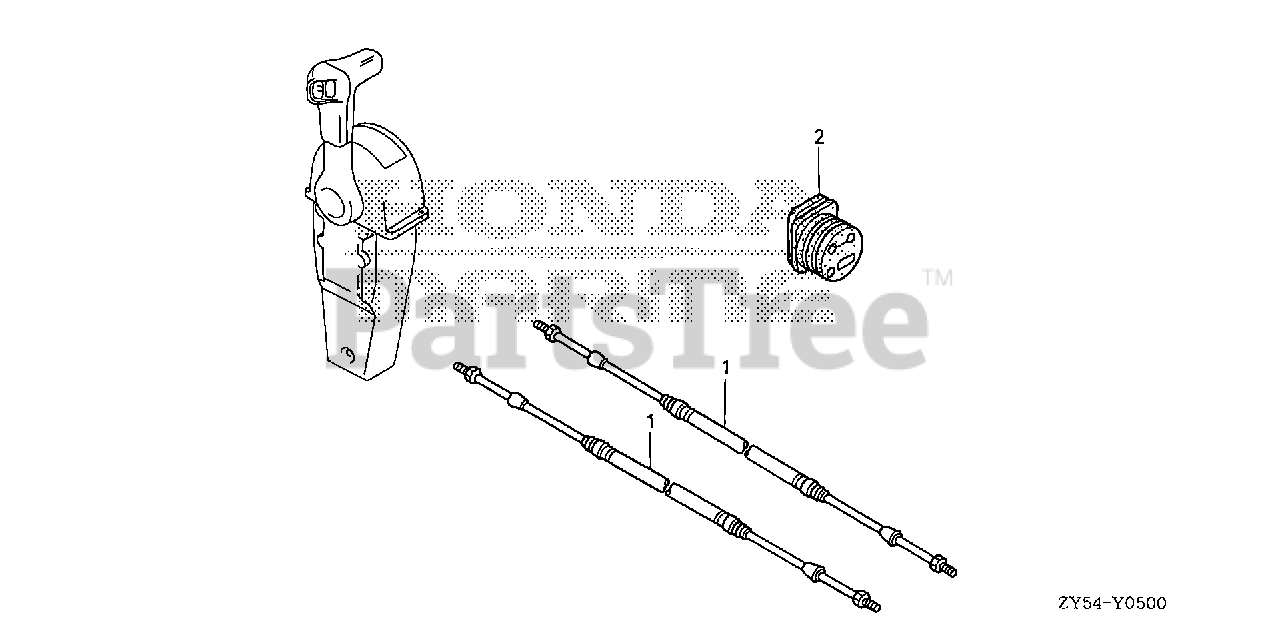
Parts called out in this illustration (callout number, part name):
1	CABLE ASSY., PUSH-PULL (33C-5FT)
1	CABLE ASSY., PUSH-PULL (33C-6FT)
1	CABLE ASSY., PUSH-PULL (33C-7FT)
1	CABLE ASSY., PUSH-PULL (33C-8FT)
1	CABLE ASSY., PUSH-PULL (33C-9FT)
1	CABLE ASSY., PUSH-PULL (33C-10FT)
1	CABLE ASSY., PUSH-PULL (33C-11FT)
1	CABLE ASSY., PUSH-PULL (33C-12FT)
1	CABLE ASSY., PUSH-PULL (33C-13FT)
1	CABLE ASSY., PUSH-PULL (33C-14FT)
1	CABLE ASSY., PUSH-PULL (33C-15FT)
1	CABLE ASSY., PUSH-PULL (33C-16FT)
1	CABLE ASSY., PUSH-PULL (33C-17FT)
1	CABLE ASSY., PUSH-PULL (33C-18FT)
1	CABLE ASSY., PUSH-PULL (33C-19FT)
1	CABLE ASSY., PUSH-PULL (33C-20FT)
1	CABLE ASSY., PUSH-PULL (33C-21FT)
1	CABLE ASSY., PUSH-PULL (33C-22FT)
1	CABLE ASSY., PUSH-PULL (33C-23FT)
1	CABLE ASSY., PUSH-PULL (33C-24FT)
1	CABLE ASSY., PUSH-PULL (33C-25FT)
1	CABLE ASSY., PUSH-PULL (33C-26FT)
1	CABLE ASSY., PUSH-PULL (33C-27FT)
1	CABLE ASSY., PUSH-PULL (33C-28FT)
1	CABLE ASSY., PUSH-PULL (33C-29FT)
1	CABLE ASSY., PUSH-PULL (33C-30FT)
1	CABLE ASSY., PUSH-PULL (33C-31FT)
1	CABLE ASSY., PUSH-PULL (33C-32FT)
2	GROMMET, CASE (LOWER) (B)
